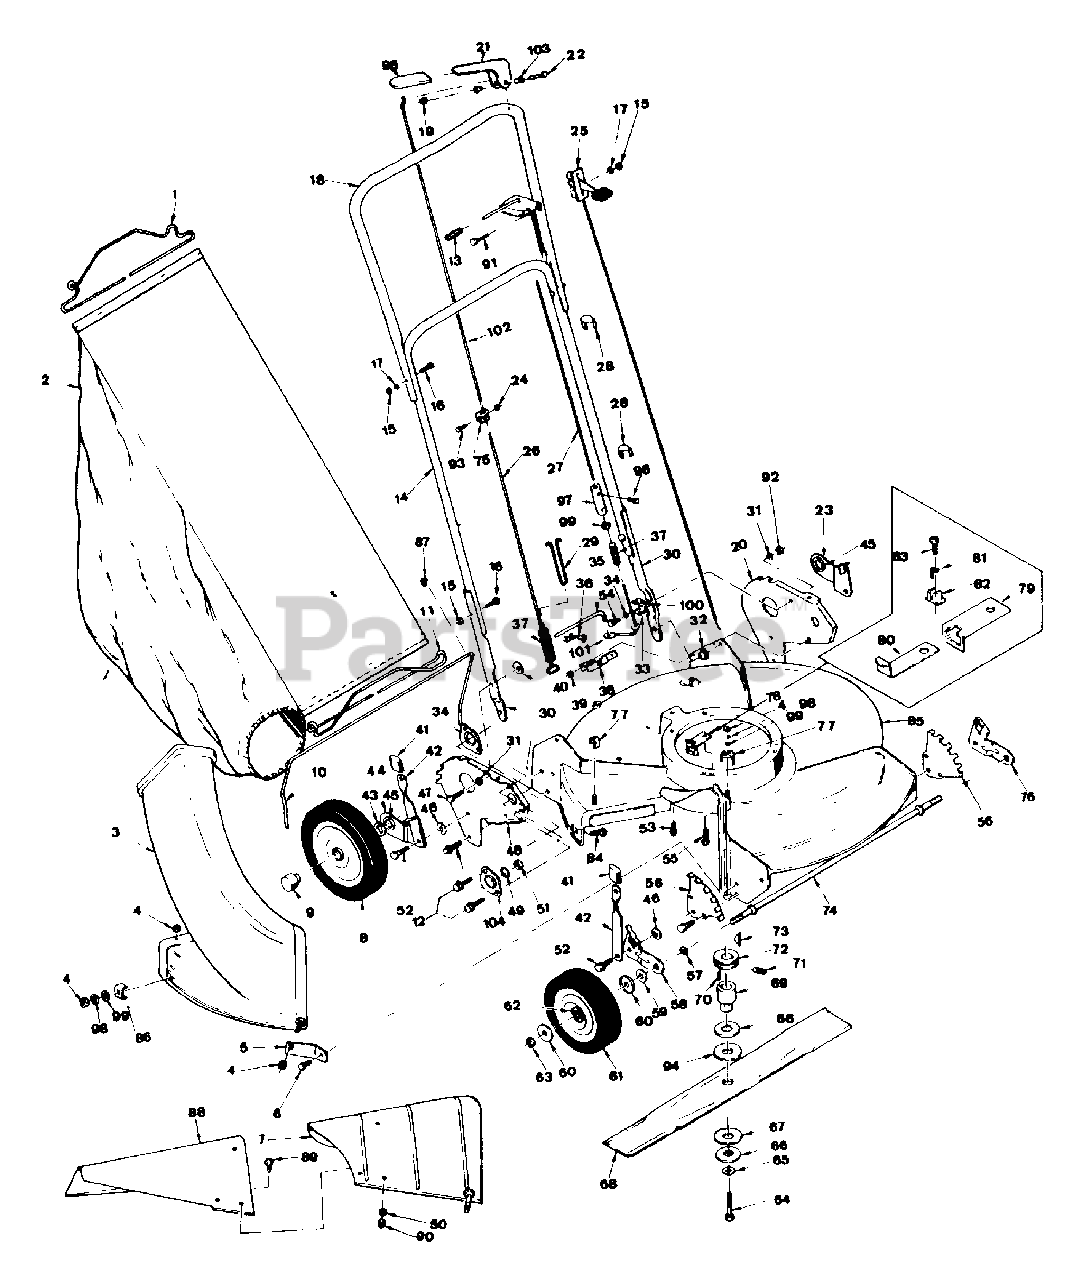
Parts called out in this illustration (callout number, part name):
1	Rear Wire
2	Grass Bag
3	Bag Chute Ass'y, V210P
3	Bag Chute Ass'y, V210PS
4	5/16 18 Hex Nut
5	Side Bracket
6	5/16-18 x 5/8 SEMS ST
7	Side Chute Assembly
8	Rear Wheel
9	Plastic Hub Cap
10	Roll Bar
11	Front Wire
12	1/4-20 x 3/8 HWST
13	Grip
14	Lower Handle
15	1/4-28 Hex Nut
16	1/4 28 x 1-1/2 HHCS, Gr. 5
17	1/4 Internal Tooth L'-Washer
18	Upper Handle Structure
19	Push Nut
20	Rear Bracket, L H.
21	Clutch Lever
22	Pin
23	Wheel Arm Rear, L.H.
24	10-24 Hex Nut
25	Throttle Control, 3 1/2 H.P.
26	Lower Pull Rod
27	Upper Speed Lever
29	Hook Spring
30	Lower Handle, Stationary
31	5/16 Int -Ext Tooth L'-Washer
32	5/16-18 Dot "T" Nut
33	ANCHOR, Speed Control
34	Holder Half
35	Clutch Rod
36	Clutch Rod Clip
37	Spring
38	Bell Crank Mount
39	5/16-18 Jam Nut
40	5/16-24 Weld Nut
41	Grip
42	Height Latch
43	3/4 Special Washer
44	Wheel Arm, Rear, L.H.
45	Bearing
46	Bolt Retainer
47	5/16-24 x 5/8 HHCS
48	Rear Bracket, R. H.
49	"O" Ring
50	No. 10 Int. Tooth L'-Washer
51	Bearing
52	5/16-18 Shoulder Screw
53	3/8-16 x 1 HWST
54	5/16-24 x 1-1/4 HHCS
55	5/16-24 x 1-5/8 HHCS, Gr. 5 (Manual Start)
55	3/8-16 x 1 HWST (Electric Start)
56	Front Bracket
58	Wheel Arm, Front, R. H.
59	Spring Washer
60	Front Hub Cap
61	Front Wheel, 7 X 1.50
62	Bearing
63	7/16-20 Jam Lock Nut
64	3/8-24 x 2, GR5 Cap Screw
65	Cone Washer
66	Clutch Washer
67	Fibre Washer
68	Cutter Bar
69	Shock Clutch Hub
70	KEY, (#6) 5/32 x 5/8" Woodruff
71	1/4-20 x 5/16 Socket Head Set Screw
72	Engine Pulley, 3-1/2 H.P.
73	Hi Pro Key
74	Front Axle
75	Clamp
76	Wheel Arm, Front, L.H.
77	Clamp
78	Interlock Assembly
79	Bracket
80	Contact
81	Tab Washer
82	Insulator
83	8-18 x 3/4 Sheet Metal Screw
84	5/16-18 x 1 Carriage Bolt
86	Clip
87	Nylon Ring
88	Side Chute Extension
89	10/32 x 5/16 RHMS
90	10/32 Hex Nut
91	1/4-28 x 2 HHCS
92	5/16-24 Lock Nut
93	10-24 x 1/2 Carriage Bolt
94	Fiber Washer
95	Grip
96	1/4-20 x 3/8 Sq. Hd Set Screw
98	5/16 Lock Washer
99	5/16 SAE Washer
101	Lower Speed Lever
102	Upper Pull Rod
103	Bushing
104	Holder Half
